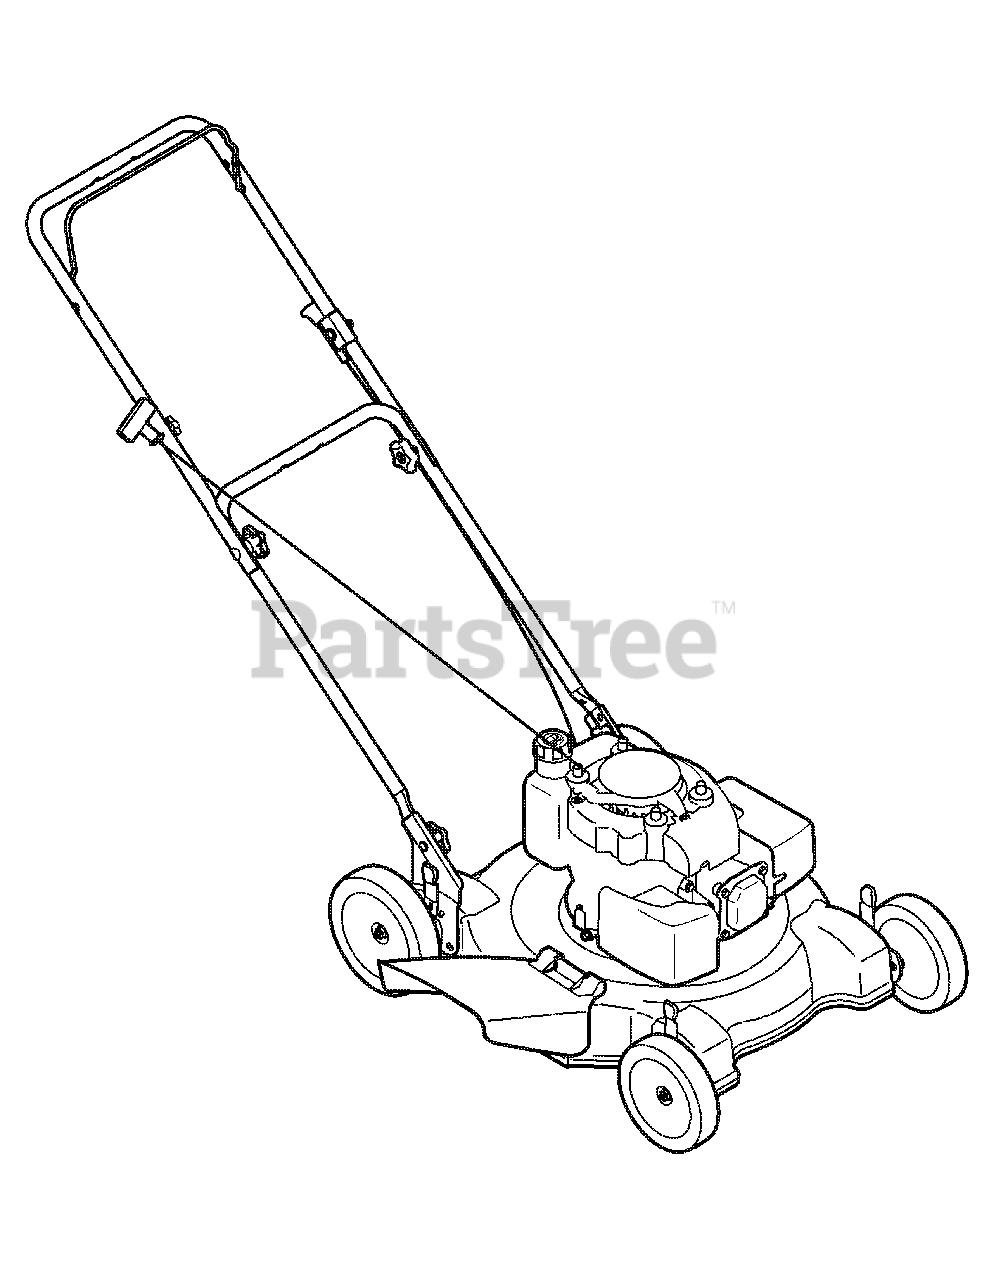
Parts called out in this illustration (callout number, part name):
NA	Pre-Filter
NA	Drive Belt
NA	Drive Cable
NA	Ignition Key
NA	Grass Bag
